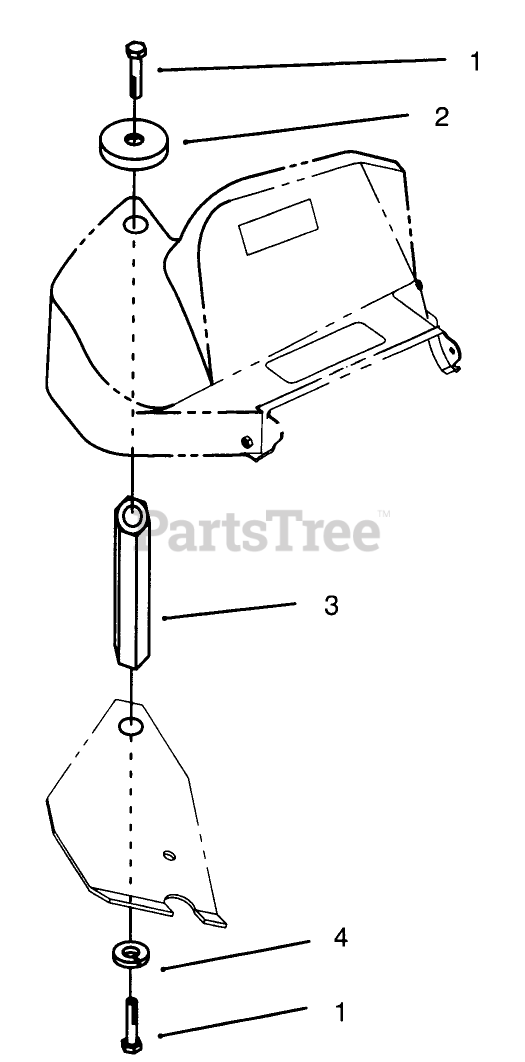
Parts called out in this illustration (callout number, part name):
1	SCREW-HH
2	WASHER-FLAT
3	SHAFT - VAC BAGGER
4	WASHER-LOCK
